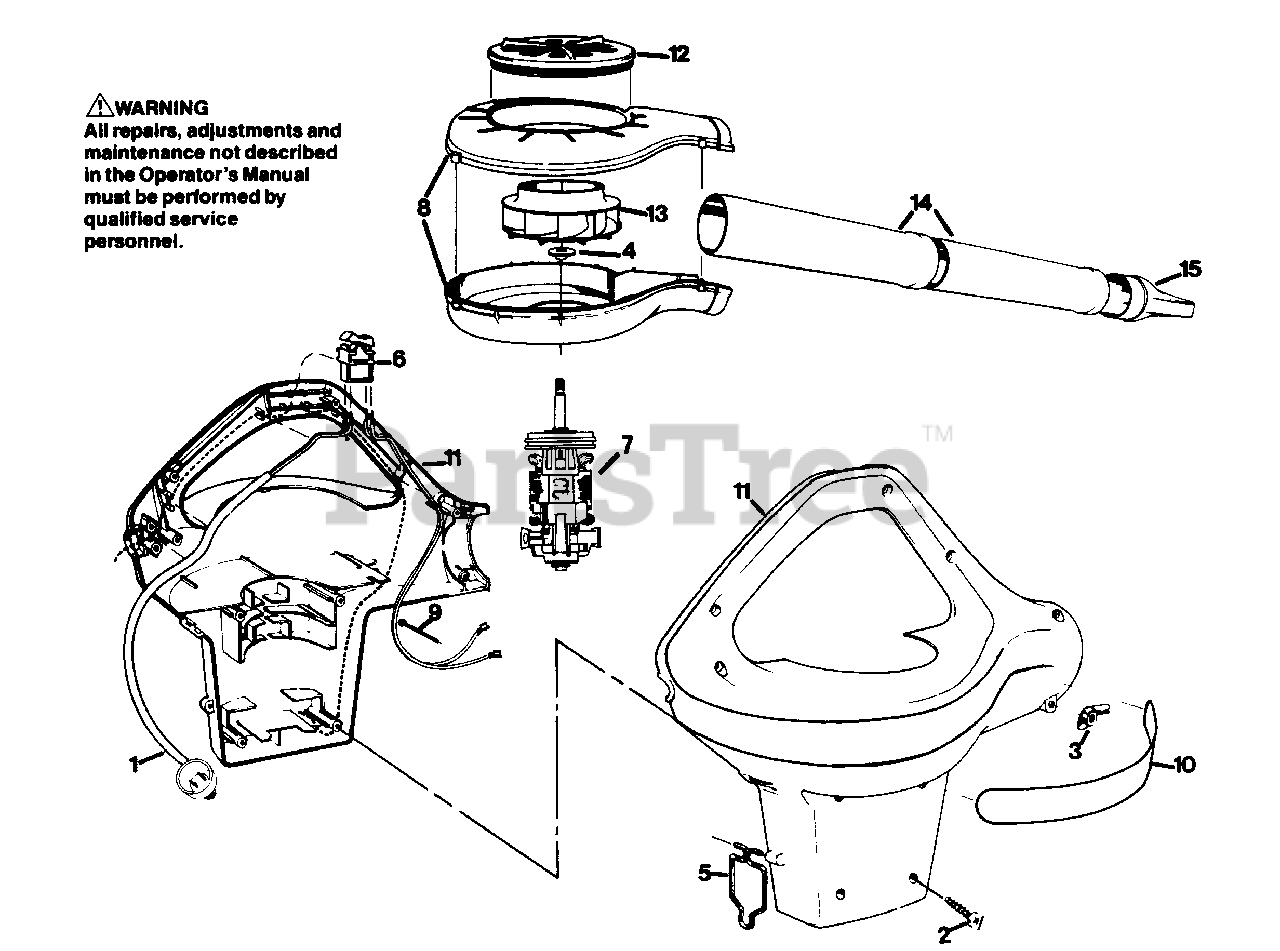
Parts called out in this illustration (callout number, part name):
2	Screw - #8 - 11 x 3/4" Pan Hd. Plastite
3	Nut
4	Spacer
7	Motor Ass'y.
8	Scroll Assembly
9	Screw - #10 - 24 x 2-3/4" Hex Hd.
11	Housing Set
12	Damper Assembly
